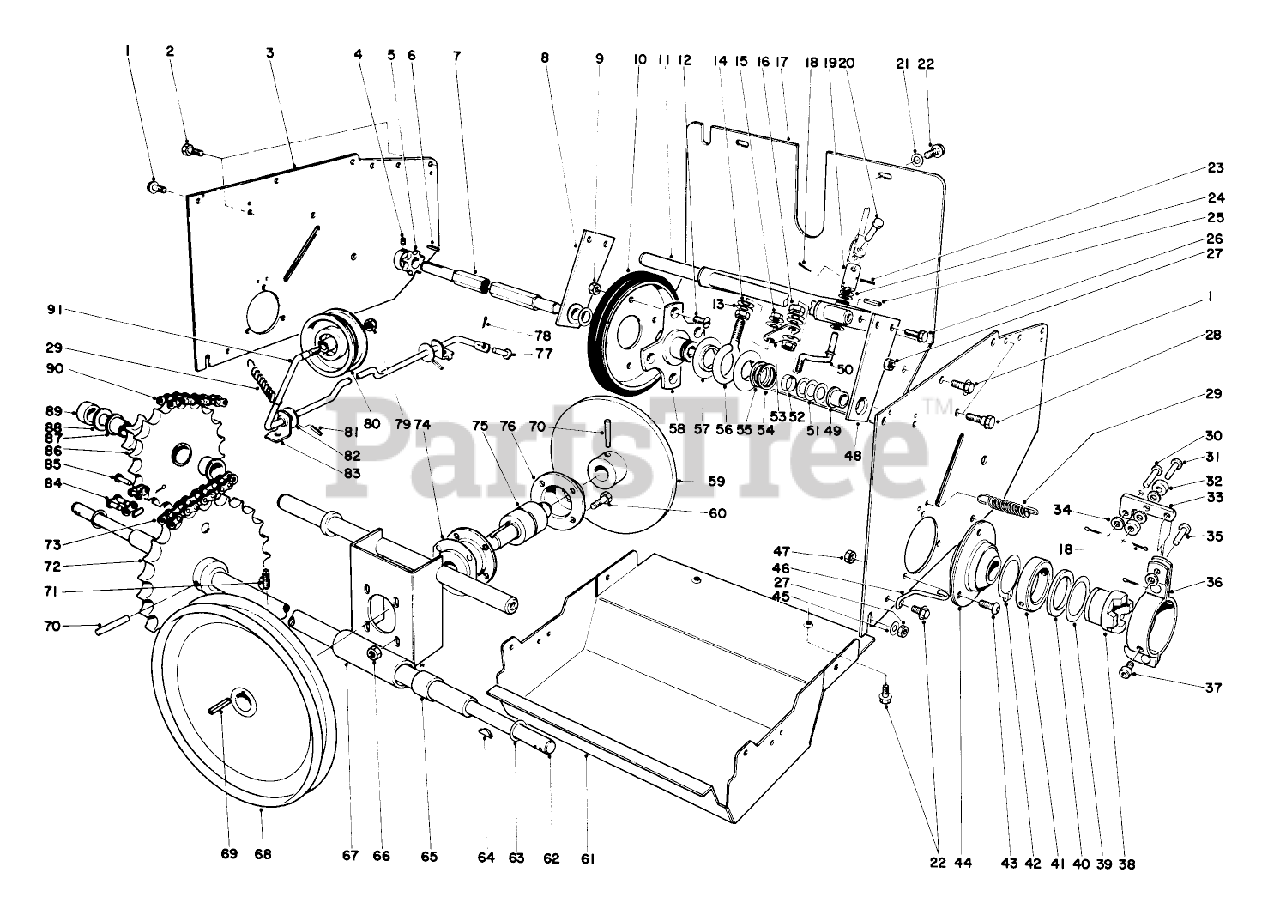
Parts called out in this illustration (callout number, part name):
1	SCREW-HHF
2	SCREW-HWH,THD ROLL
5	SPROCKET
8	RH SHAFT MT & BSHG
12	SCREW-FH, S
13	WASHER-FLAT
14	WASHER-SPRING
15	NUT-LOCK, FLANGE
17	REAR COVER *R
18	PIN-COTTER
21	WASHER-FLAT
23	PIN-SPRING
25	PIN-ROLL
29	EXTENSION SPRING
30	PIN-CLEVIS
31	PIN-CLEVIS
34	WASHER-FLAT
35	PIN-CLEVIS
37	SCREW-HSH
39	THRUST WASHER
40	THRUST BEARING
42	RING-RETAINING, EXTERNAL
43	SCREW-HSBH
45	WASHER-FLAT
49	BUSHING
50	CONNECTION ROD
51	WASHER-FLAT
53	SHIFT ROD PIVOT
55	WASHER-THRUST
56	SLIDER RING COLLAR
59	FRICTION PLT WA
60	SCREW-HH
61	LOWER SHIELD *R
63	WASHER
65	BUSHING
66	NUT-KEPS
70	Groove Pin
71	SCREW-SET, SQH
76	HOUSING BEARING
77	PIN-CLEVIS
78	PIN-COTTER
80	PULLEY-IDLER
81	PIN-ROLL, SLOTTED
82	WASHER-FLAT
84	LINK-CONNECTING
85	1/4 OFFSET LINK
88	WASHER-THRUST
90	1/4 X 42 CHAIN W/LINK
91	Auger Clutch Rod
